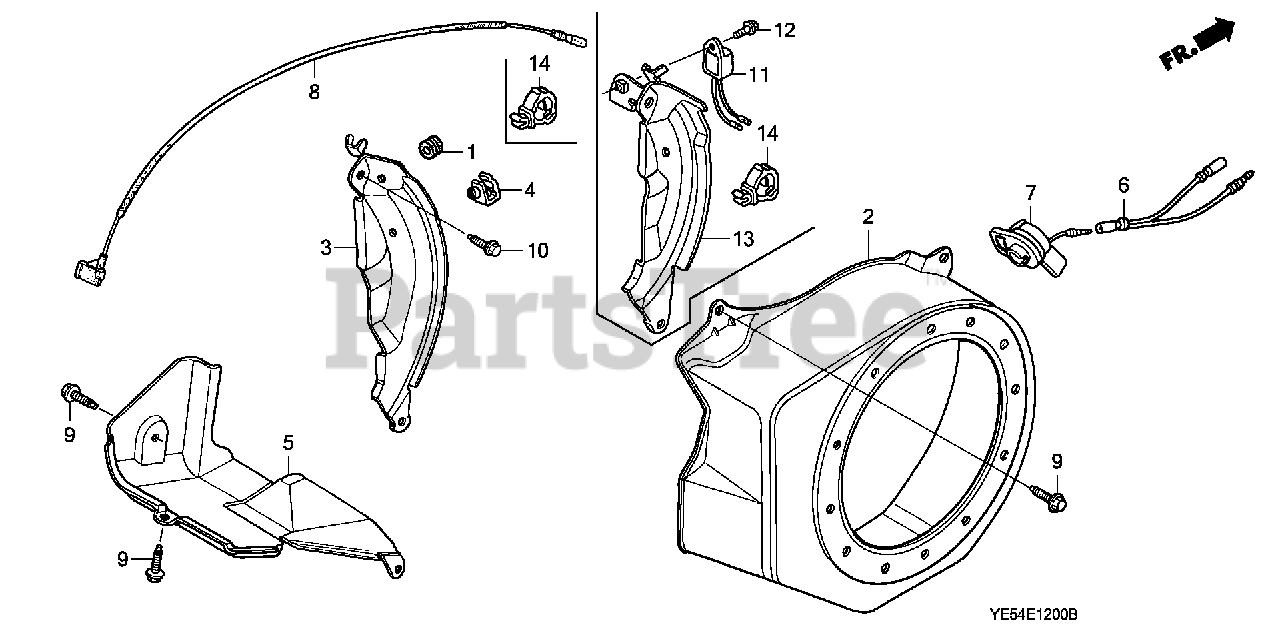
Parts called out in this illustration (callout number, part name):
1	GROMMET, ADJUSTING COVER
2	COVER, FAN *R280* (POWER RED)
3	PLATE, SIDE (OIL ALERT)
3	PLATE, SIDE
4	CLAMP, CORD
6	SUB-HARNESS
7	SWITCH ASSY., ENGINE STOP
8	WIRE, STOP SWITCH (370MM)
9	BOLT, FLANGE (6X12) (CT200)
10	BOLT, FLANGE (6X20) (CT200)
11	ALERT UNIT, OIL
12	BOLT, FLANGE (6X8)
13	PLATE, SIDE (OIL ALERT)
14	CLIP, HARNESS
